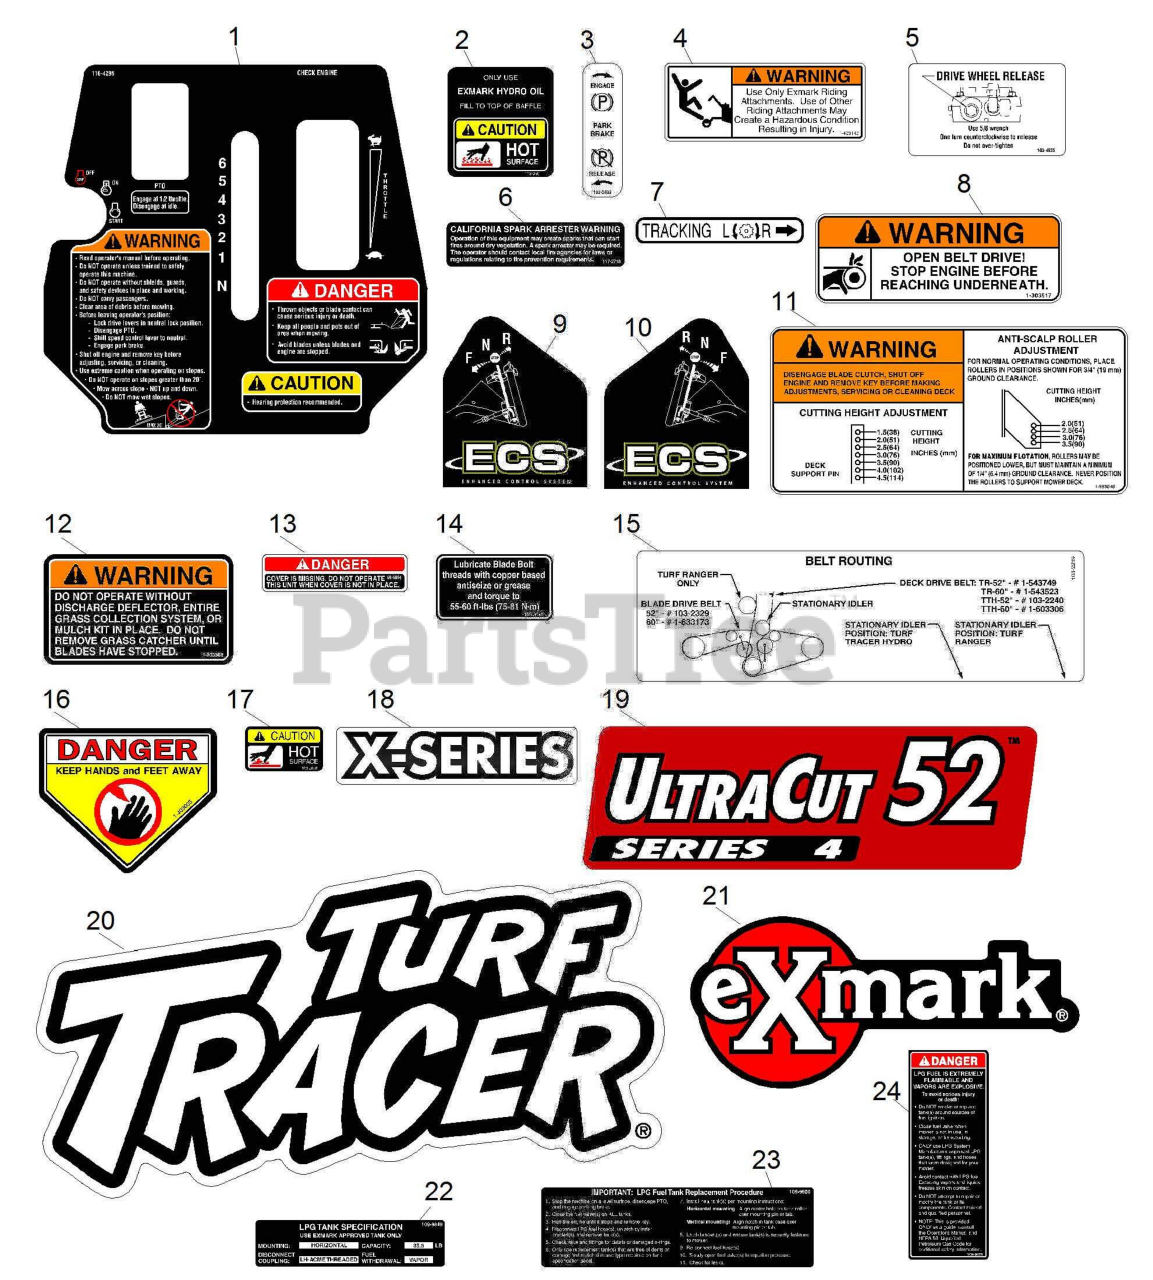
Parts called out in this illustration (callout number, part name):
1	DECAL,CONSOLE TTX
2	DECAL-HYDRAULIC TANK
3	DECAL,PARKING BRAKE
4	DECAL,SULKY WARNING
5	DECAL,DRIVE RELEASE
6	DECAL-ARRESTER, SPARK
7	DECAL,TRACKING ADJUST
8	DECAL,BELT DRIVE
9	DECAL,LH ECS INSTRUCTION
10	DECAL,RH ECS INSTRUCTION
11	DECAL,ANTI SCALP
12	DECAL-WARNING, DISCHARGE
13	DECAL-COVER, MISSING
14	DECAL,BOLT TORQUE
15	DECAL,BELT ROUTING
16	DECAL-DANGER
17	DECAL-CAUTION
18	DECAL-X-SERIES
19	DECAL,ULTRACUT 52 SERIES
20	DECAL,TTH MODEL
21	DECAL,EXMARK LOGO
22	DECAL,LPG TANK SPEC HORIZ
23	DECAL-TANK REPLACEMENT
24	DECAL-LPG WARNING
